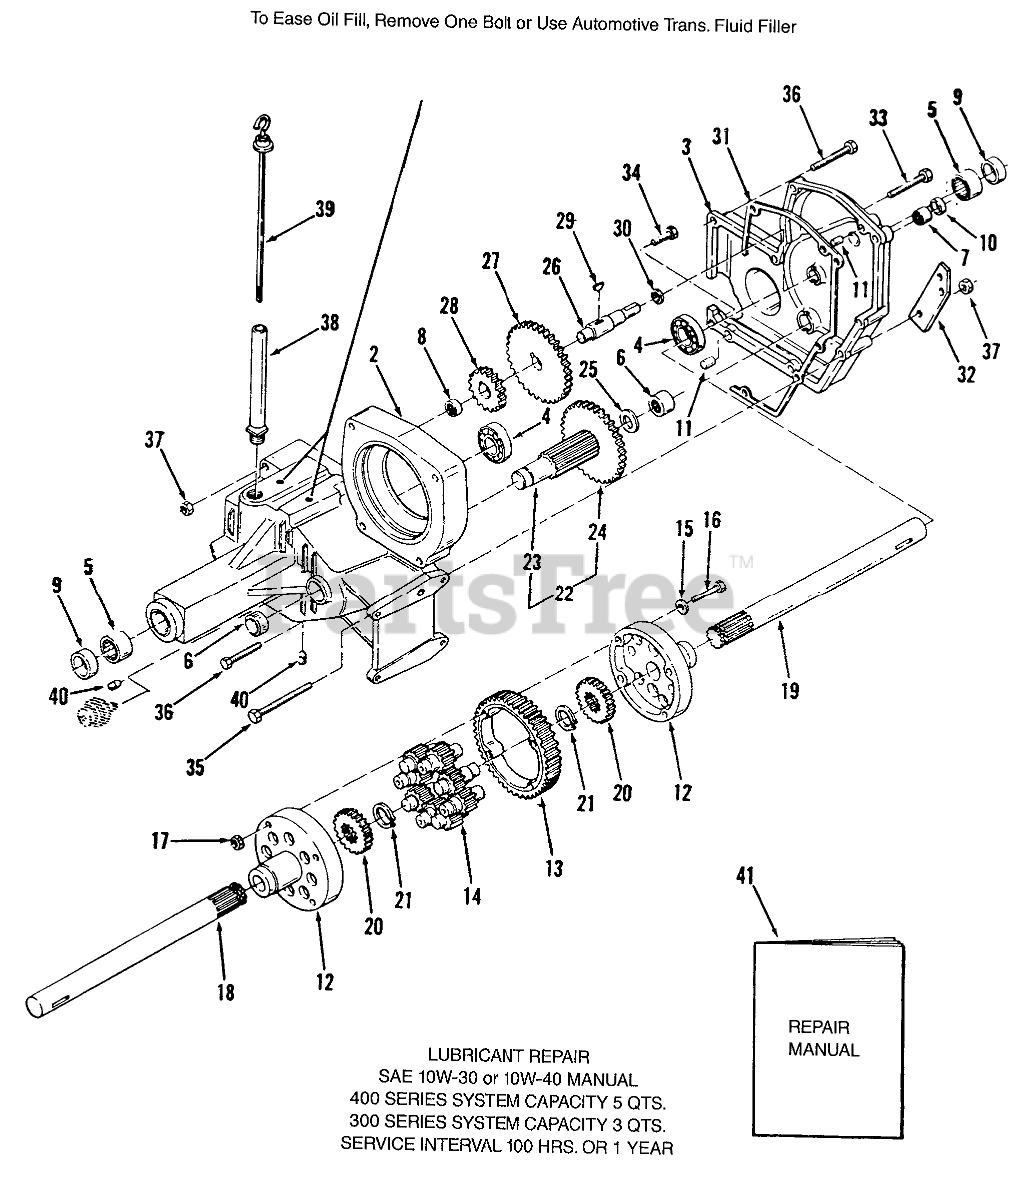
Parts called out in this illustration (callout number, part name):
2	CASE-TRANS RH
3	CASE TRANS LH
4	BEARING-BALL
5	BEARING
6	BEARING-NEEDLE
7	NEEDLE BEARING
8	BEARING-NEEDLE
9	SEAL-OIL
10	Seal
11	PIN-LOCATING
12	END CAP-DIFFERENTIAL
13	GEAR-DIFFERENTIAL RING, 43T
14	GEAR-PINION, 11T
15	WASHER
16	BOLT-HEX
18	AXLE-REAR RH
19	AXLE-REAR LH
20	GEAR-AXLE DIFFERENTIAL
21	RING-SNAP
22	GEAR ASM
23	PINION SHAFT
25	WASHER-THRUST
26	SHAFT GEAR
27	Gear 44 Tooth
28	GEAR 22T
29	Key
30	Race Thrust
31	GASKET-TRANSMISSION
32	BRACKET-BRAKEB
33	Bolt
34	Bolt
35	Hex Bolt
36	HHCS
37	NUT
38	NIPPLE-TRANS FILL
39	Dipstick
40	PLUG 1/4 PIPE ALLEN
41	Repair Manual
